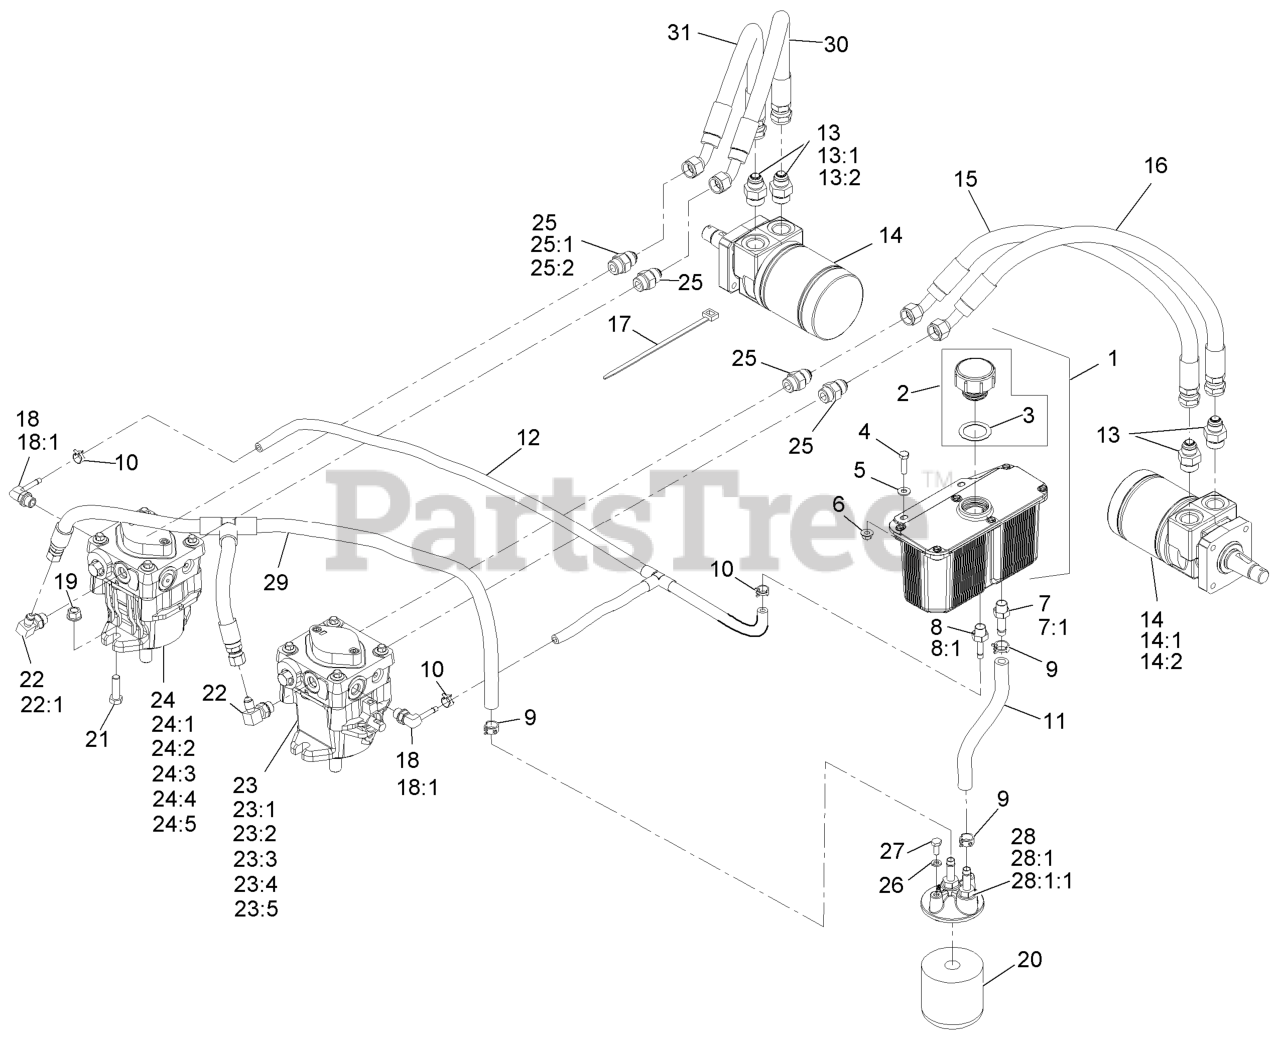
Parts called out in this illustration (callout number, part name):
1	HYD RESERVOIR ASM
2	KIT,HYD RES CAP W/GASKET
3	GASKET-CAP
4	SCREW-HH
5	WASHER-FLAT
7	ADAPTER-STRAIGHT
8	ADAPTER-STRAIGHT
9	CLAMP-HOSE
10	CLAMP-HOSE
11	HOSE,CASE DRAIN RH
12	HOSE-CASE DRAIN ASM
13	FITTING-STRAIGHT
14	HYD MOTOR ASM
14:1	SEAL KIT
14:2	BEARING AND SEAL KIT
15	HOSE,HYDRAULIC W/COVER
16	HOSE,HYDRAULIC W/COVER
17	TIE-PLASTIC
18	ELBOW-90 DEG
19	NUT-FLANGE
20	FILTER-25 MICRON, BI-DIRE
20	ELEMENT-FILTER, WINTER
21	SCREW-HH
22	FITTING-ELBOW, 90 DEG
23	PUMP-HYD PE RH TTH
23:1	INPUT SHAFT KIT
23:2	BEARING-THRUST
23:3	CYLINDER BLOCK KIT
23:4	SEAL OVERHAUL KIT
23:5	KIT, 10CC PUMP KIT
24	PUMP-HYD PE LH TTH
24:1	INPUT SHAFT KIT
24:2	BEARING-THRUST
24:3	CYLINDER BLOCK KIT
24:4	SEAL OVERHAUL KIT
24:5	KIT, 10CC PUMP KIT
25	FITTING-STRAIGHT
26	WASHER-LOCK
27	SCREW-HH
28	FILTER HEAD ASM
28:1	ADAPTER-STRAIGHT
29	ASM,CHARGE HOSE
30	HOSE,HYDRAULIC W/COVER
31	HOSE, HYDRAULIC W/COVER
